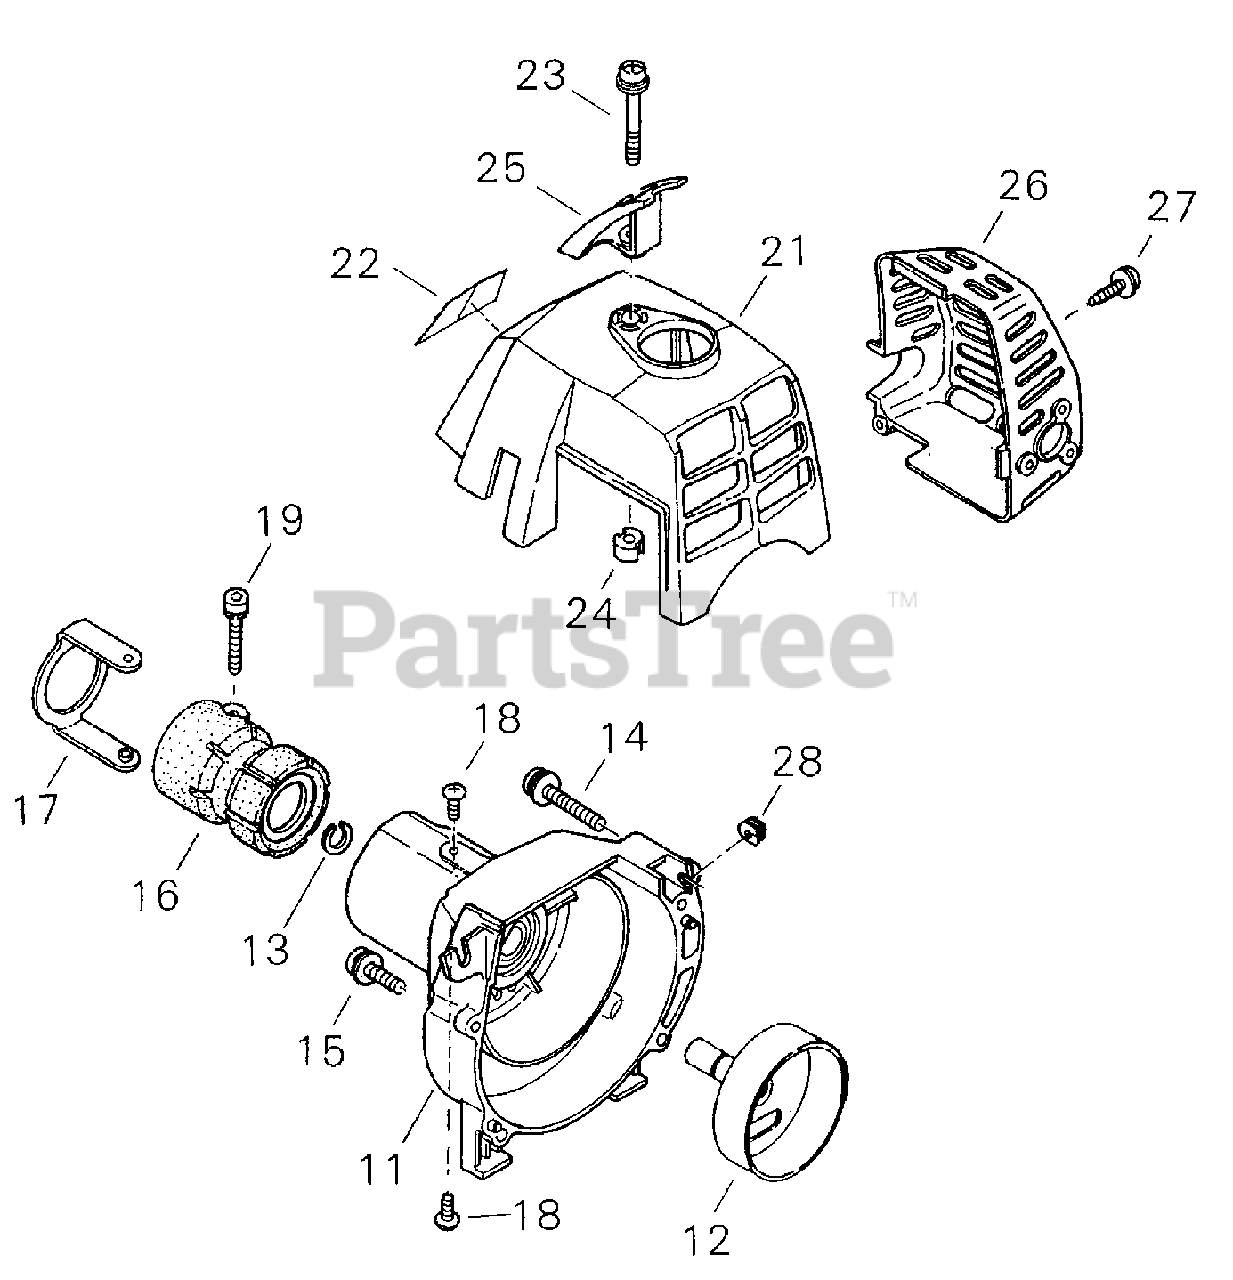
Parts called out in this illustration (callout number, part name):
3-11	COVER, FAN
12	DRUM, CLUTCH
13	RING, SNAP Ø12
14	SCREW M5×30
15	SCREW M5×16
16	CUSHION, AV
17	STOPPER
18	SCREW, ADHESIVE M4×8
19	BOLT M5×22
21	COVER, ENGINE
22	LABEL, MODEL
23	SCREW
24	INSULATOR
25	PROTECTOR, SPARK PLUG
26	COVER, MUFFLER
27	SCREW M5
28	GROMMET, LEAD
